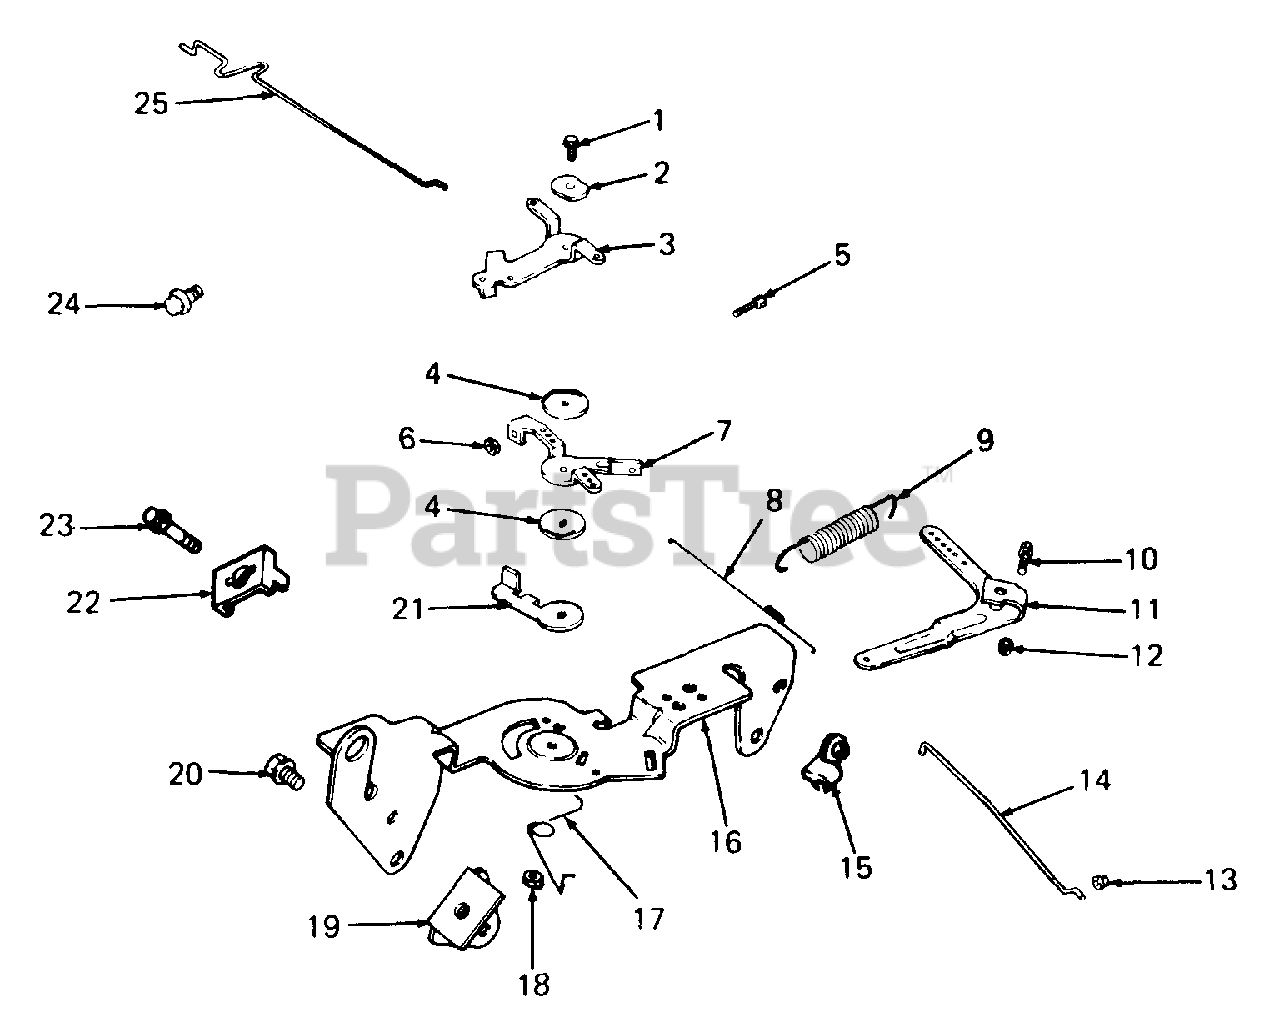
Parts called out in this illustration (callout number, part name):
1	Screw, M5 X 0.8 X 20
2	Washer, Spring
3	Lever, Choke
5	Screw, M4 X 0.7 X 27.9
6	Nut
7	Lever, Throttle Control
8	Spring, Linkage
9	Spring, Governor
10	Screw, M6 X 1.0 X 25
11	Lever, Governor
12	Nut, M6 X 1.0
13	Bushing, Linkage Retaining
14	Linkage, Throttle
15	Bushing, Linkage Retaining
16	Bracket, Control
17	Spring, Choke Return
18	Nut, M5 x 0.8
19	Bracket, Support
20	Screw, M6 X 1.0 X 16
21	Lever, Throttle Actuator
22	Clamp, Cable
23	Screw, M5 X 0.8 X 16
24	Screw, M5 X 0.8 X 10
25	Linkage, Choke
